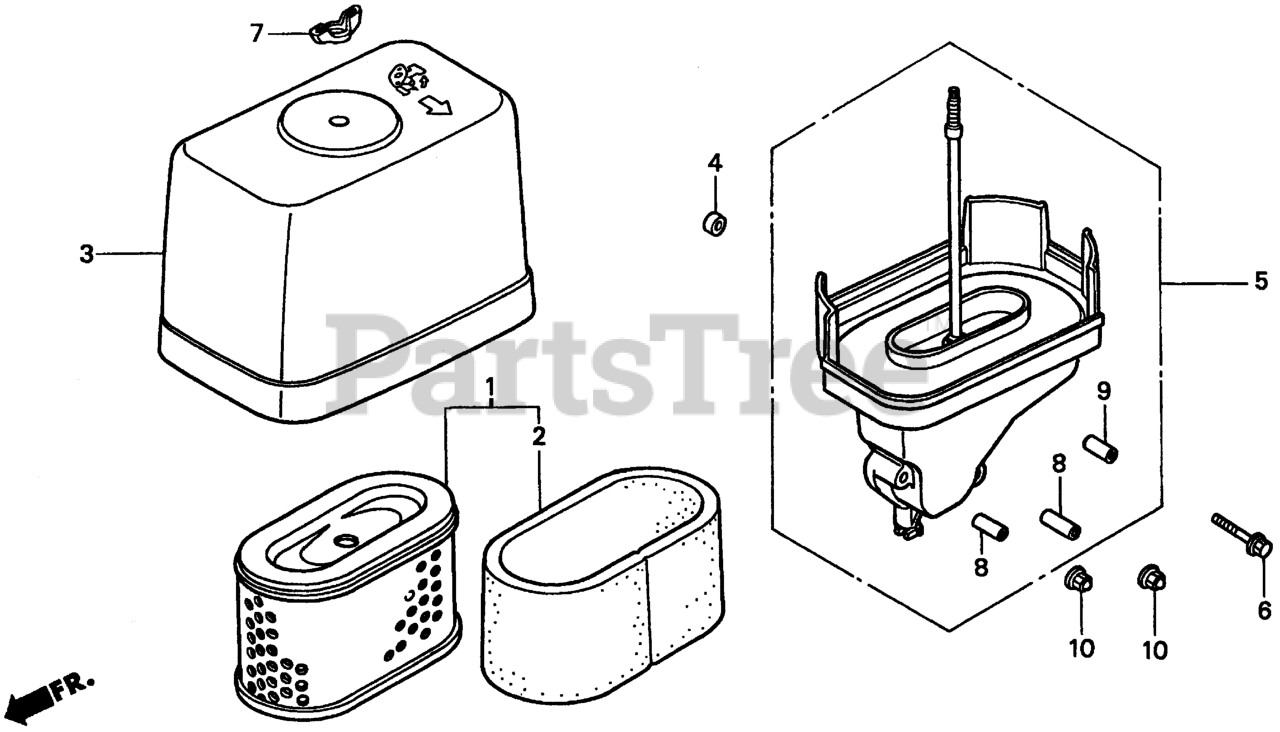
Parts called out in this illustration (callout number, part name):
1	ELEMENT, AIR CLEANER (PLASTIC BASE)
2	FILTER (OUTER)
3	COVER, AIR CLEANER
4	SPACER, AIR CLEANER ELBOW
5	ELBOW COMP., AIR CLEANER
6	BOLT, FLANGE (6X57)
7	WINGNUT, TOOL BOX SETTING
8	COLLAR, AIR CLEANER
9	COLLAR, AIR CLEANER
10	NUT, FLANGE (6MM)
